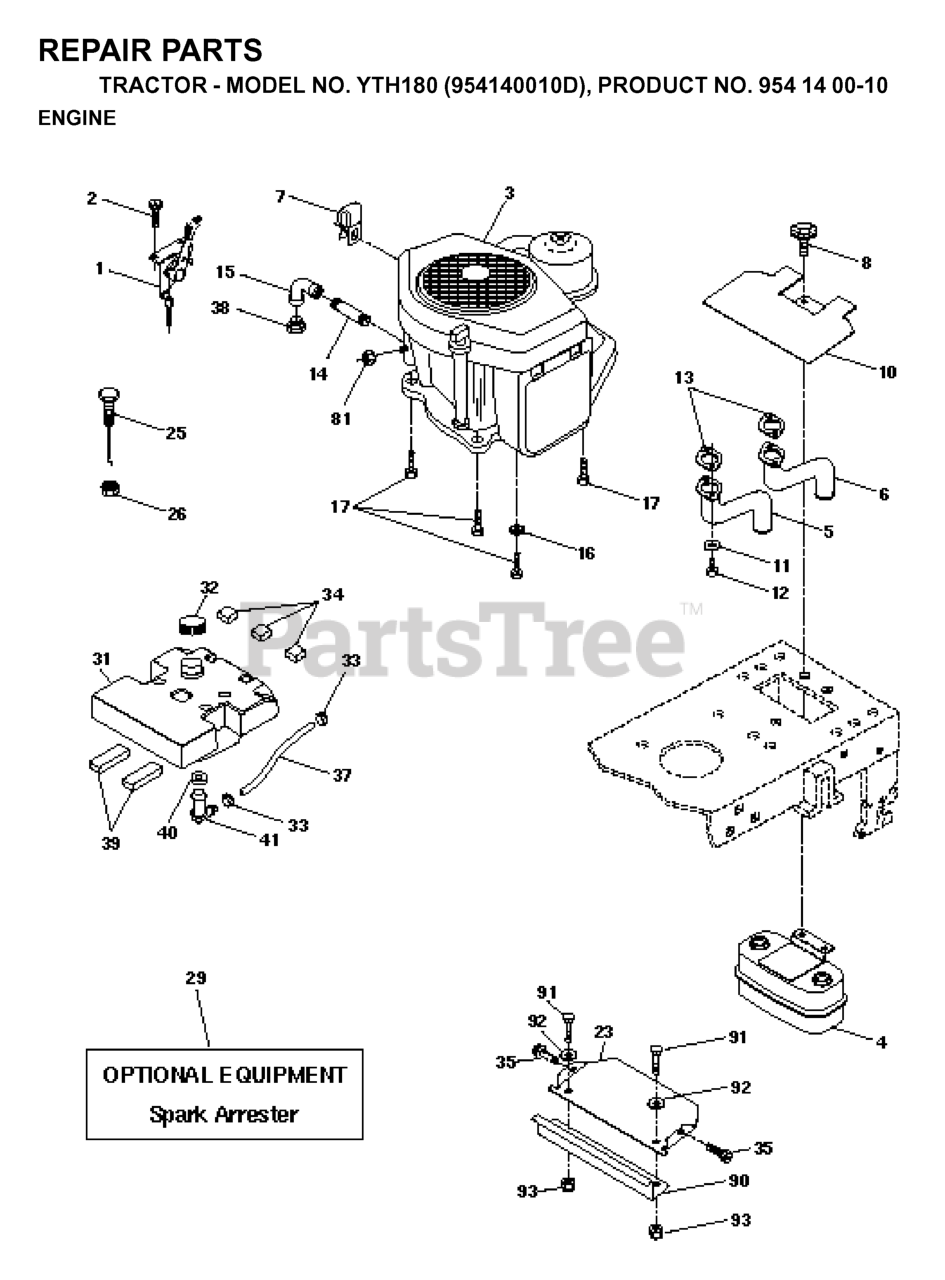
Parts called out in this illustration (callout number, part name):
1	CONTROL THROTTLE
2	SCREW LT
4	MUFFLER.TWIN.CYL.LOW.TONE
5	RP.PIPE-EXHAUST LH
6	RP.PIPE-EXHAUST RH
7	CLIP T
8	BOLT HEX WASHER HD 5/16-18
10	RP SHIELD HEAT MUFFLER
14	Nipple, Pipe 3/8 NPT x 4-1/2
15	ELBOW
16	LOCKWASHER
17	SCREW LT
23	SHIELD HEAT
25	CONTROL, CHOKE
26	Nut Keps 3/8 - 24 UNF
29	KIT.SPARK ARRESTOR 794945 B&S
31	TANK.FUEL(3.5.GAL)
32	FUEL CAP
33	HOSE CLAMP
34	PAD-SPACER LT
35	SCREW.THDROL.5/16-18X3/4.TTY
37	HOSE T
39	PAD IDLER TI
40	BUSHING OUTLET T
41	STEM FUEL TANK
81	NUT FLANGE 1/4-20 STARTER NUT
91	BOLT
93	NUT T
